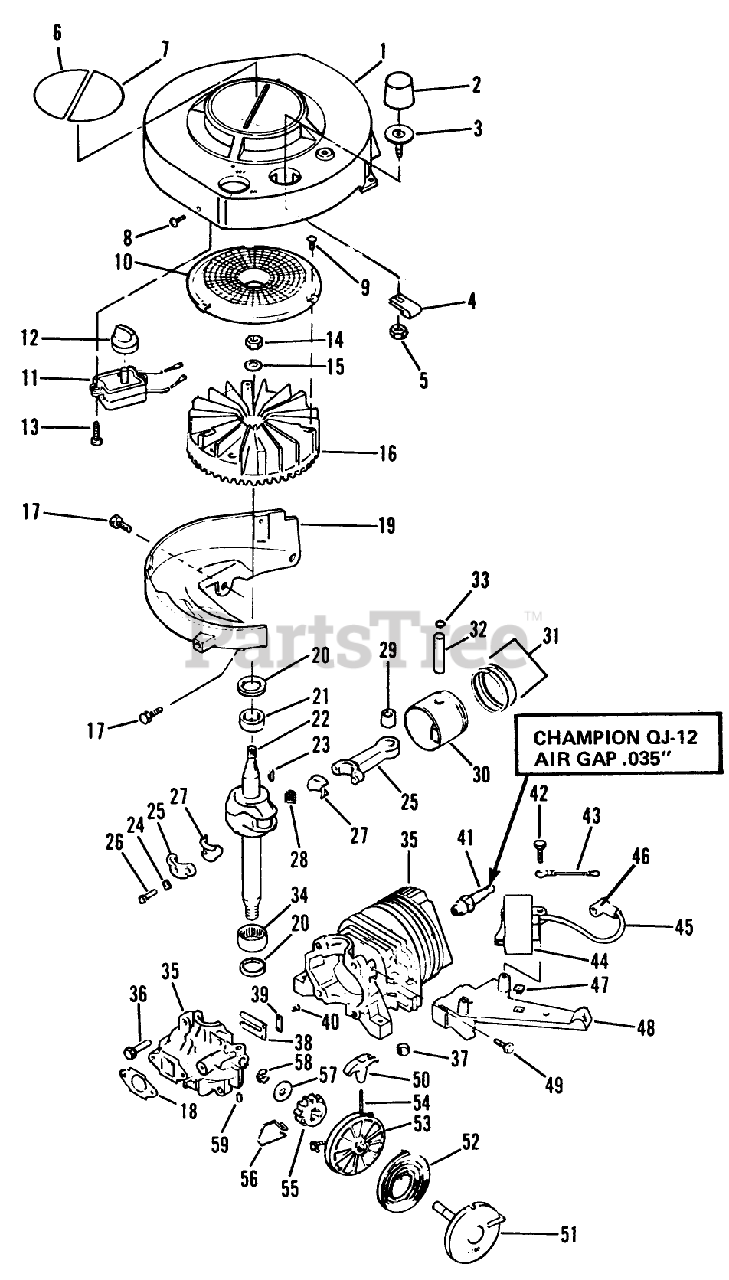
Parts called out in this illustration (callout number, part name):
5	LOCKNUT S
6	Decal-Fuel
7	Decal-Start
8	SCREW F
9	SCREW F
12	SWITCH KNOB
17	SCREW-SEMS
18	GASKET CARB S
21	BEARING V
27	LINER ASM
29	BEARING AY F
33	RING-RETAINING
34	BEARING V
36	SCREW S
37	PLUG-CORE VF
39	PLATE-BACKUP, REED
45	HT LEAD&COVER XEV
47	NUT-CLIP
50	HANDLE STARTER S
52	SPRING S
56	SPRING F
57	WASHER S
59	SET SCREW
